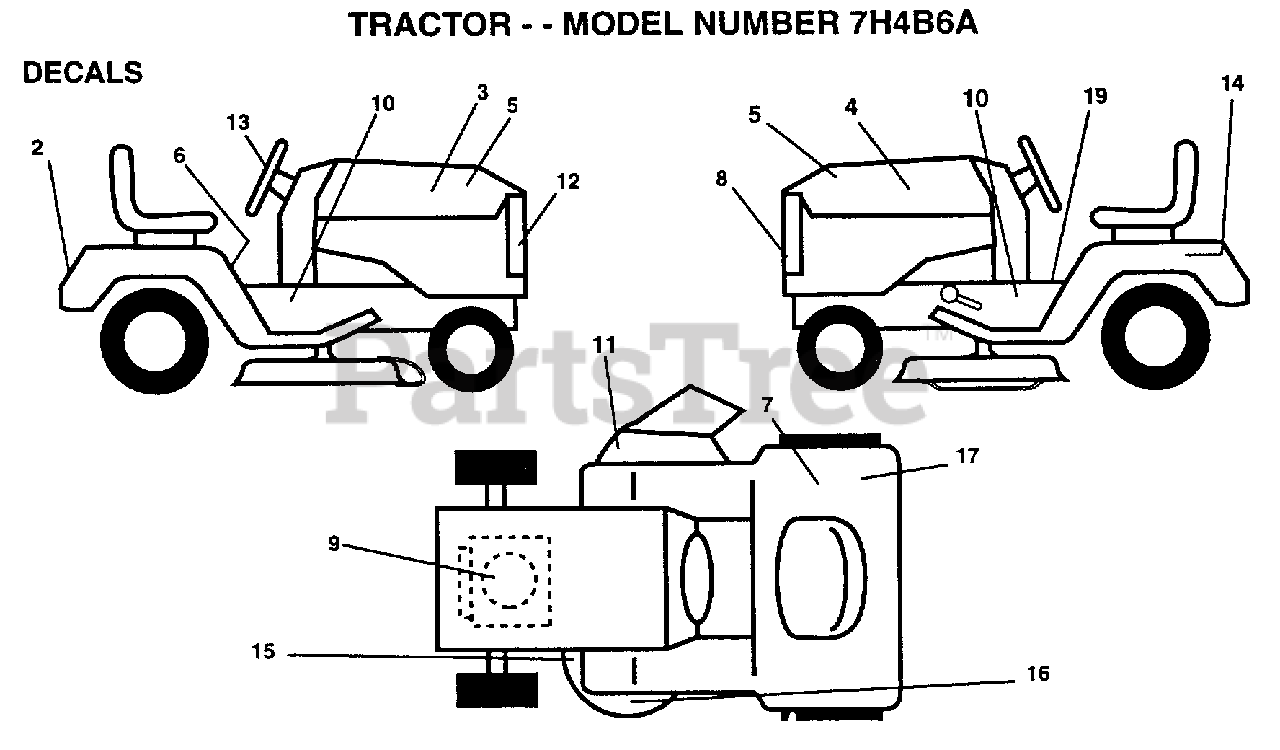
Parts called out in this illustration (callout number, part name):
2	FENDER DECAL
3	DECAL HOOD RH RLY
4	DECAL HOOD LH RLY
6	DECAL.READ.O.MANU
7	DECAL.EURO.ST.CE.
9	DECAL, HP ENGINE
10	DECAL CHAS 42 HYD
11	DECAL.DANGER.CUTF
12	GRILL DECAL
13	"DECAL,STR WHL"
14	DECAL.BATRY.3-3908
15	DECAL
19	DECAL BRAK PARK
